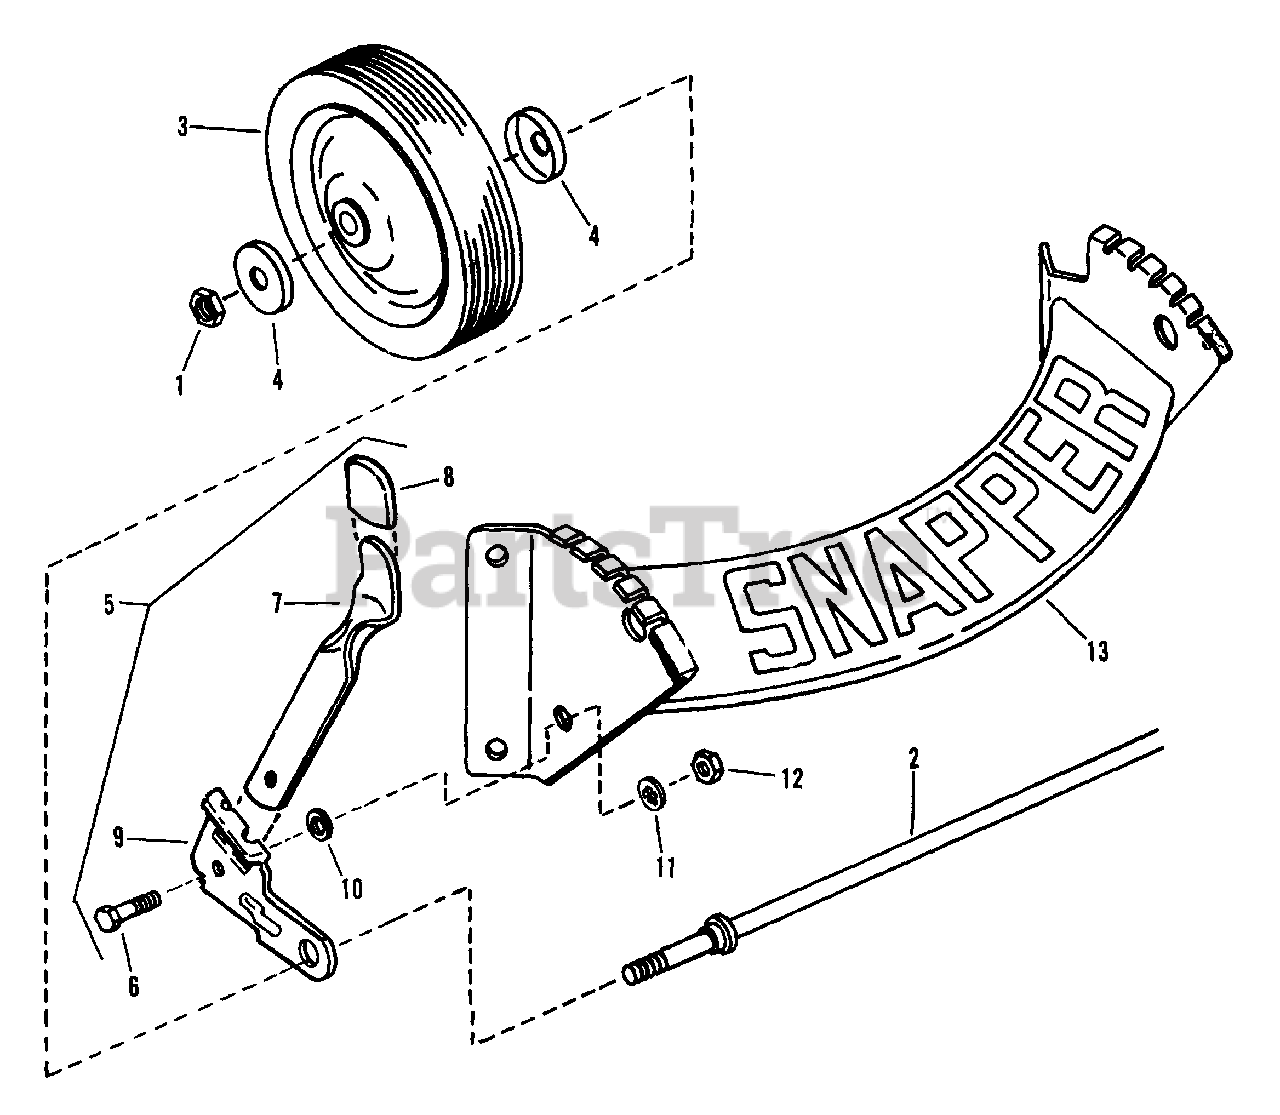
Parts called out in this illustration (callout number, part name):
1	NUT, 7/16-20 Hex Centerlock
2	AXLE
3	WHEEL, Front, 7 x 1.75 Steel Rim
4	HUB-CAP
5A	ARM ASSEMBLY, Right Wheel
6	BOLT, 5/16-18 Shoulder
7	LATCH, Height
8	GRIP
9A	ARM, Right Wheel
10	RETAINER, 5/16 Bolt
11	WASHER, 5/16 Int. Toothlock
12	NUT, 5/16-18 Hex
13	BRACKET, Front Wheel
